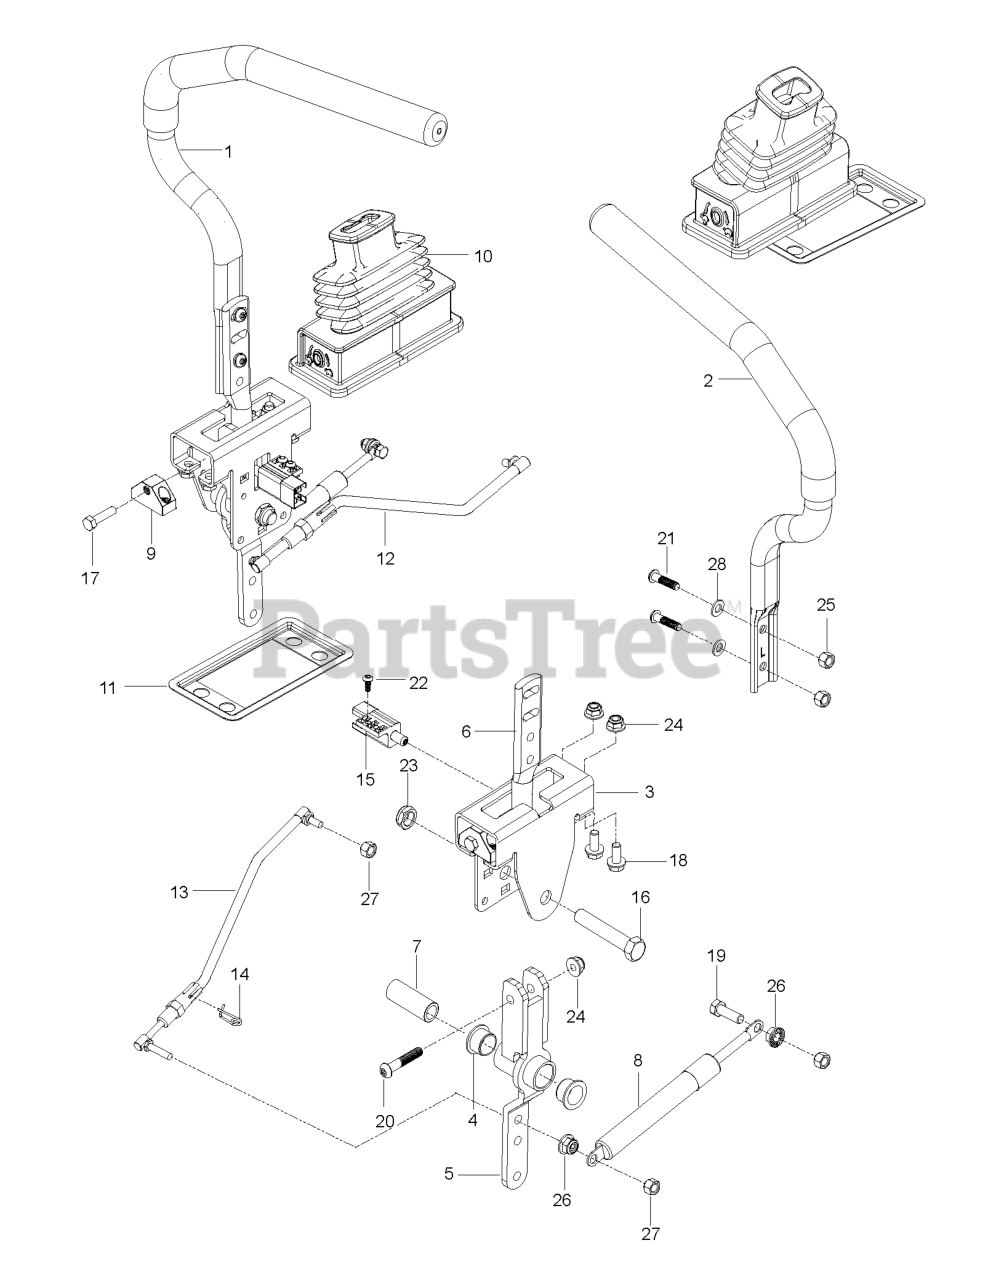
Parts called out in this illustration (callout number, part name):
1	TUBE.LEVER.CONTROL.ZTR.RT.428
2	TUBE.LEVER.CONTROL.ZTR.LT.428
3	BRACKET.CONTROLS.ZTR.X431
4	BEARING, FLANGE
5	LEVER CONTROL PIVOT
6	CONTROL.LEVER.HANDLE
7	SPACER.PIVOT.CONTROL
9	BLOCK TRACKING CONTROL ZTR
10	BOOT.STEERING.LEVER
11	CONTROL.BOOT.FLANGE.X431
12	ROD.ASM.RH.ADJUSTABLE
13	ROD.ASM.LH.ADJUSTABLE
14	RETAINER.CLIP.SPRING.S
15	SWITCH.INTLK.RZ.RFRSH.BUTTON
16	HCS 1/2-13 X 2-3/4 GD 5 ZD
17	SCREW.SHAKEPROOF.1.25.BLACK
18	HHFS 5/16-18 X 3/4
19	HCS 5/16C X 1
20	SCREW.CAP.SOCKET.6PT.5/16-18
21	BUTTONHEAD.5/16-18X1.125.BLACK
22	SCREW.BUTTONHD.10-24X1/2.(2 2)
23	NUT 1/2-13 HEX JM NYL
24	5/16-18 NYLOC FLANGE NUT
25	NYLOCK.NUT.5/16-18 BLACK
26	NUT 5/16C WHIZ
27	NUT.71038.31-18.HEX.NYLOCK
28	WASHER
29	WASHER.11/32ID.11/16OD.116THIC
